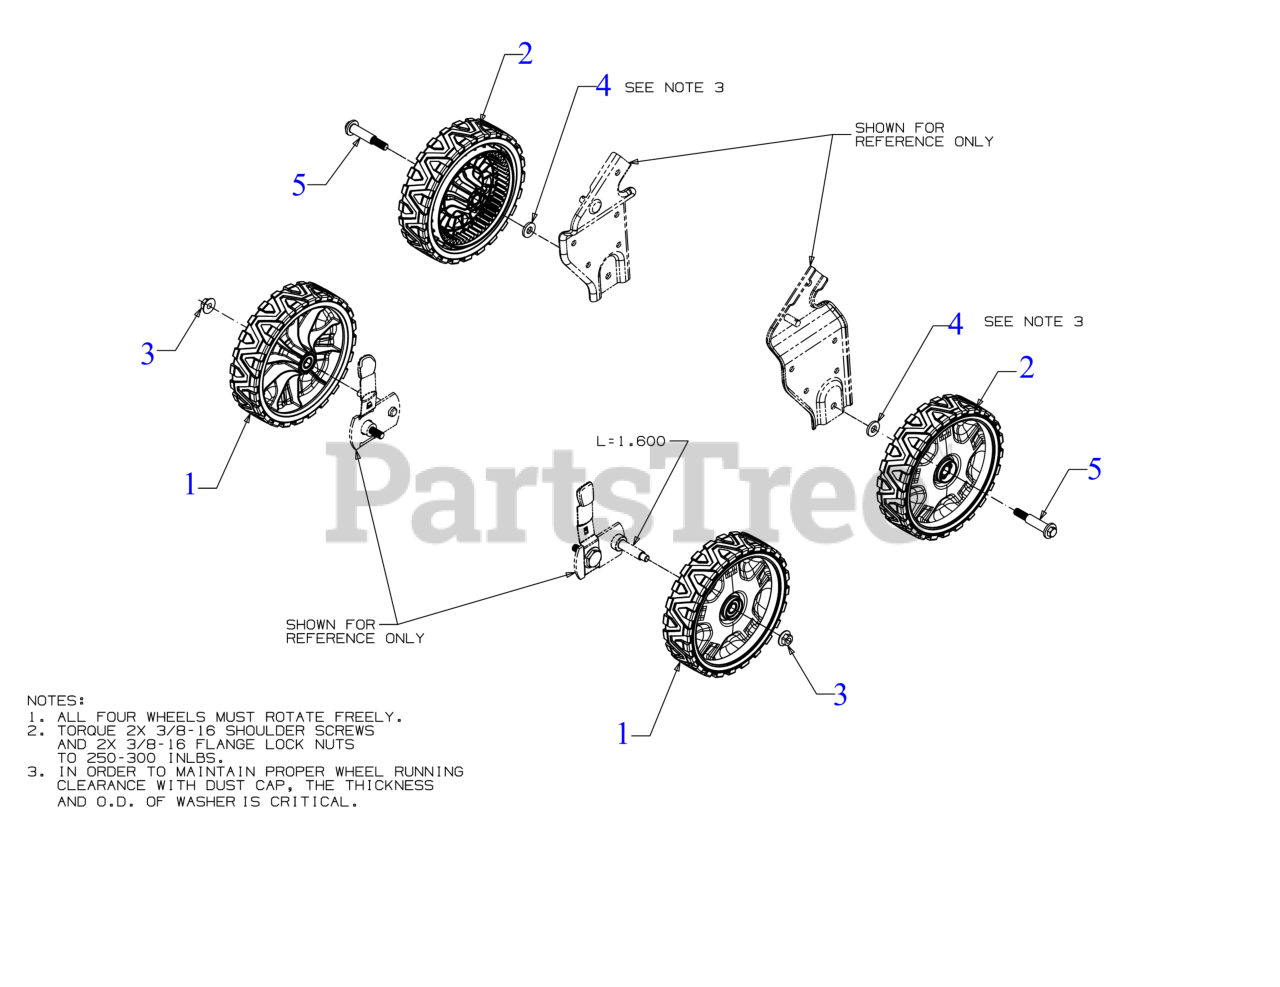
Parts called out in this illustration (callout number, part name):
1	WHEEL ASSEMBLY (8 x 2)
2	WHEEL ASSEMBLY (8 x 2)
3	FLANGE LOCK NUT
4	FLAT WASHER
5	SHOULDER SCREW .496X1.605 3/8-16
